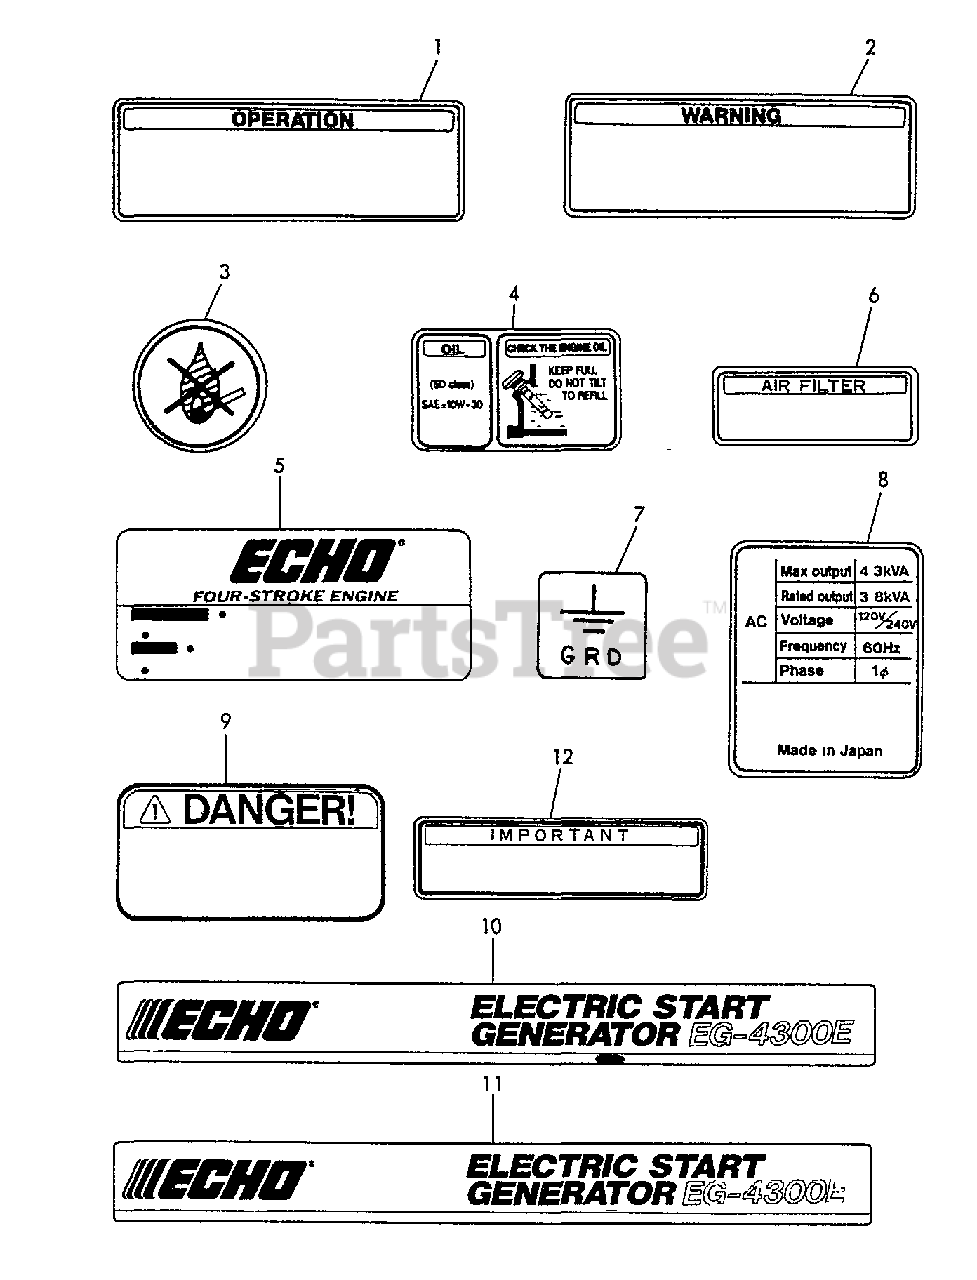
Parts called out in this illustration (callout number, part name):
1	LABEL
2	LABEL - WARNING
3	LABEL, NON FIRE
4	LABEL, OIL
5	LABEL, ECHO
6	LABEL - AIR FILTER
7	LABEL, EARTH
8	LABEL - GENERATOR
9	LABEL DANGER
10	LABEL - GENERATOR
11	LABEL - GENERATOR
12	LABEL - IMPORTANT
